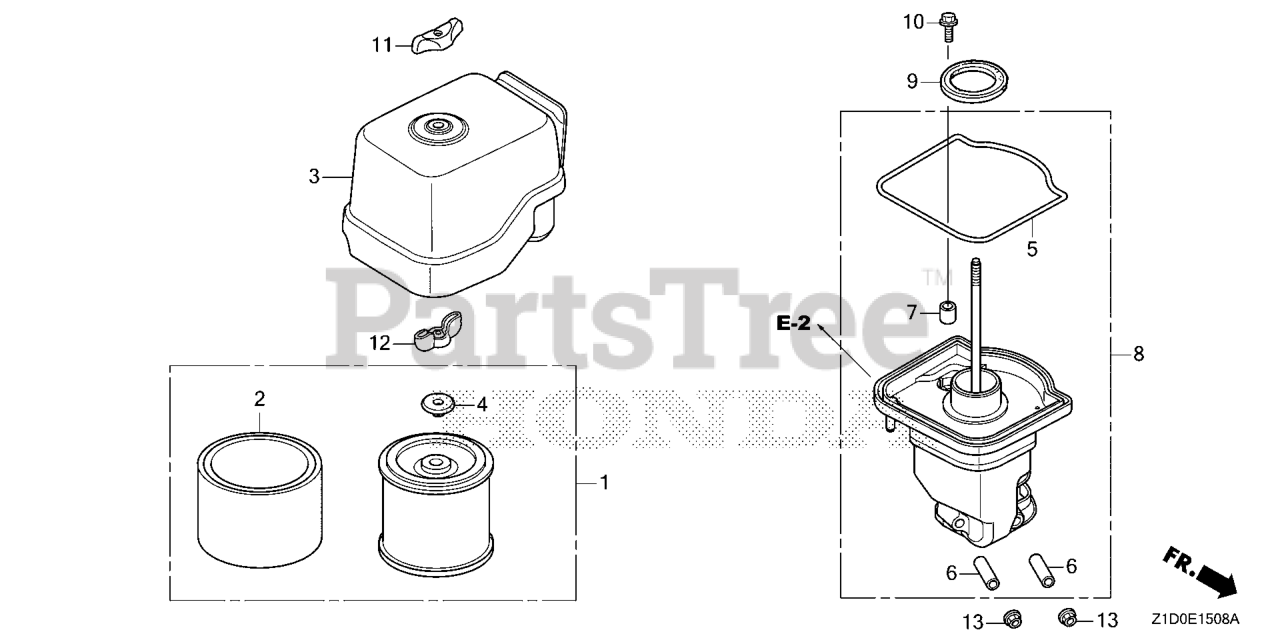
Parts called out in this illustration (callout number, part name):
1	ELEMENT, AIR CLEANER
2	FILTER (OUTER)
3	COVER ASSY., AIR CLEANER (CYCLONE)
4	GROMMET, AIR CLEANER
5	SEAL, AIR CLEANER COVER
6	COLLAR, AIR CLEANER
7	COLLAR B, AIR CLEANER
8	ELBOW, AIR CLEANER
9	GASKET, AIR CLEANER HOUSING
10	BOLT-WASHER (6X22)
11	NUT, AIR CLEANER
12	WINGNUT, TOOL BOX SETTING
13	NUT, FLANGE (6MM)
